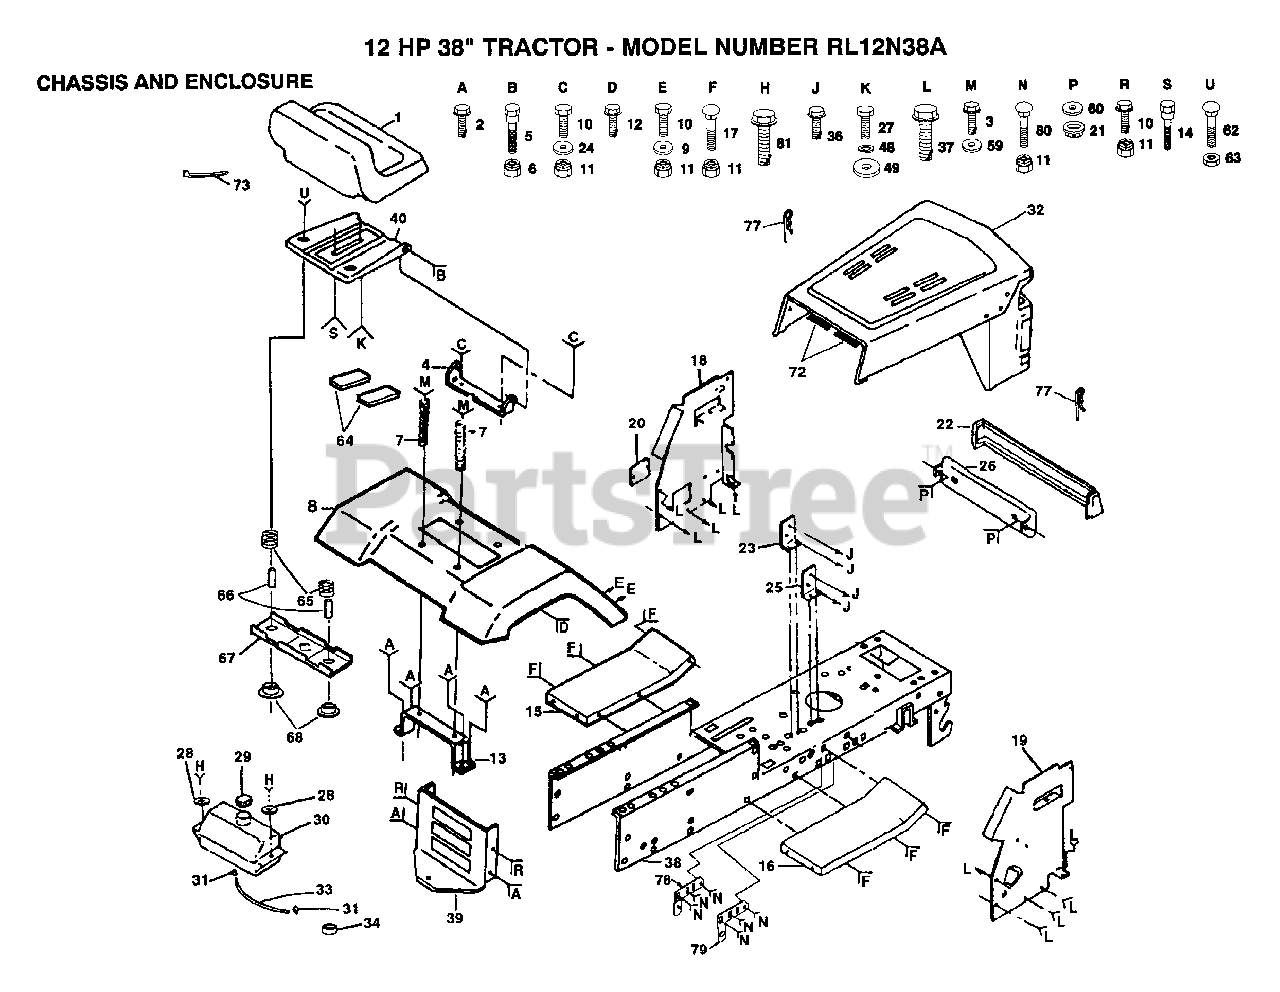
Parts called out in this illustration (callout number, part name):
2	SCREW
3	SCREW GTV
7	SPRING COMPRESSIO
9	WASHER
12	SCREW LT
14	"BOLT,SHOULDER"
15	FOOTREST LH
16	FOOTREST
17	BOLT
18	PANEL DASH LH
20	COVER ACCESS
21	PAL NUT LT
23	SWITCH BRACKET
24	WASHER
25	BRACKET LT
27	BOLT
28	WASHER
30	TANK.FUEL.LT.
31	HOSE CLAMP
32	HOOD/GRILL ASM
33	FUEL LINE T
36	SCREW
37	SCREW LT
39	DRAWBAR LT/YT
48	LOCKWASHER
49	WASHER
59	WASHER
60	WASHER PM
64	STRIP FORM
65	SPRING
66	SPACER SPLIT
67	BRKT SWITCH
68	BUSHING
73	WIRE TIE
77	SPRING.RETAINER
78	BRKT ASM PIVOT LH
79	BRKT ASM PIVOT RH
80	BOLT
81	SCREW HEX CRT
